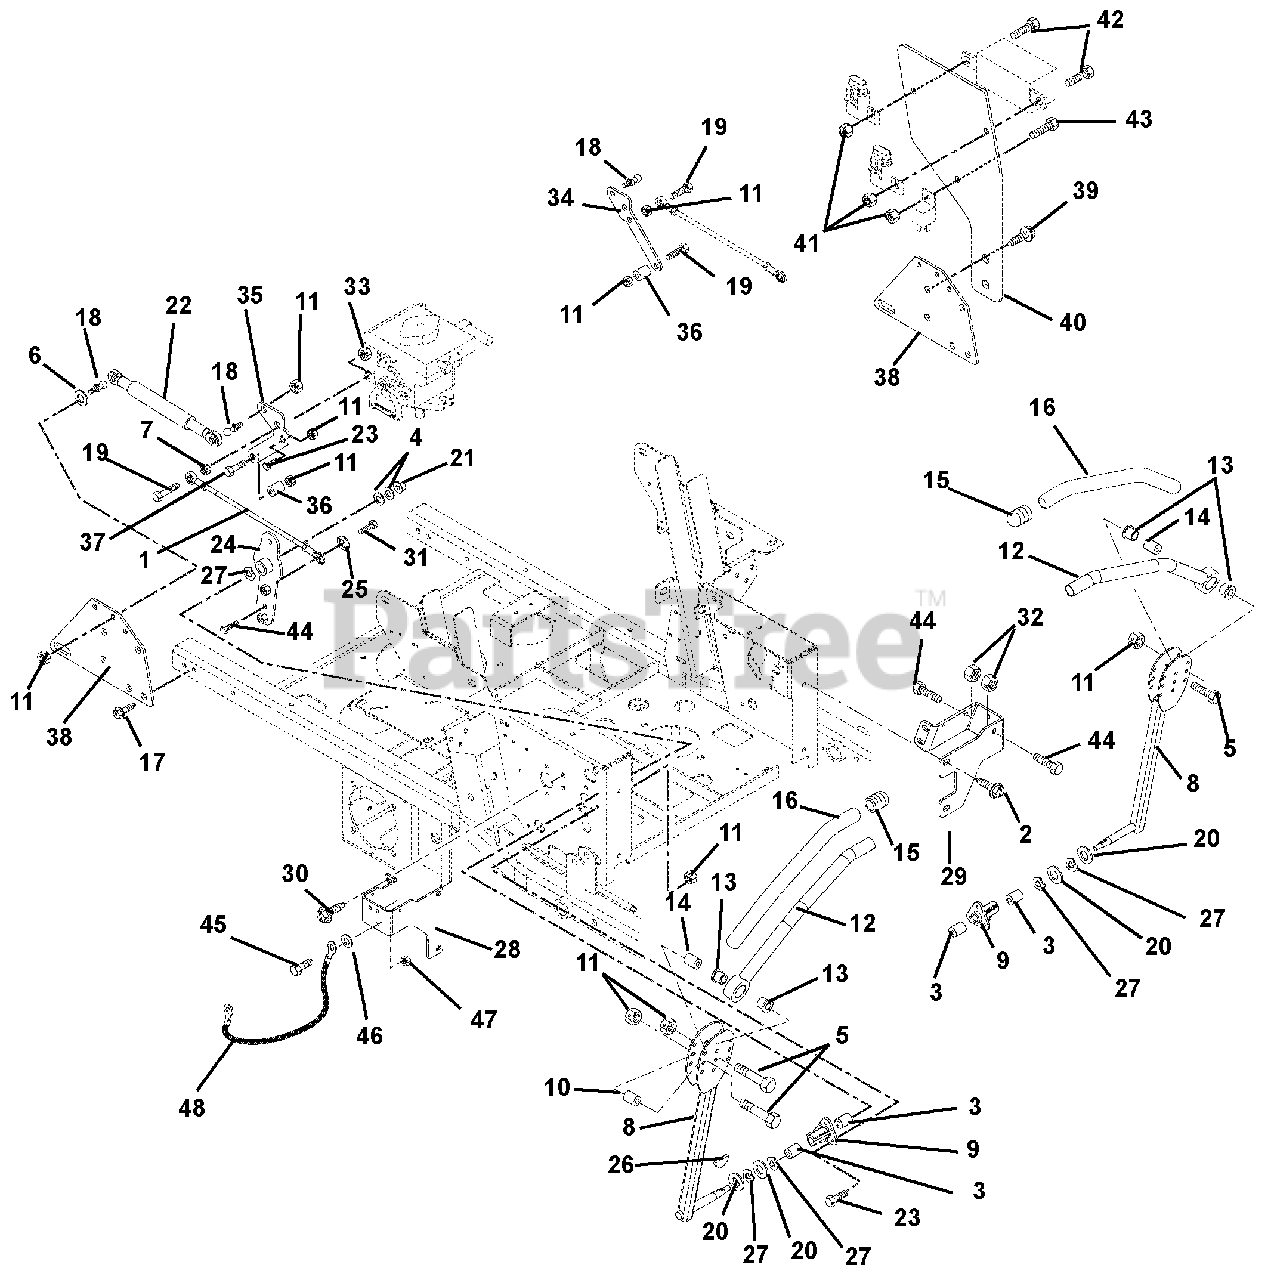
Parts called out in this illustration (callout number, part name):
1	Assembly, Steering Rod .38 Rod x 7.60
2	Screw, Tapping .38-16 x .75 Hex Washer Head
3	Bushing .625 x .75 x .50
4	Washer, Flat Steel .403 x .812 x .065
5	Bolt, Hex .31-18 x 1.75 Grade 5
6	Washer, Flat Steel .344 x .688 x .065
7	Nut, Hex .38-16
8	Control Arm
9	Bushing, Flange
10	Eccentric
11	Nut, Locking Top Flange .31-18
12	Handle Weldment Left-Hand
13	Bushing, Flange Nylon .762 x 1.48 x .44
15	Caplug, Handlebar
16	Grip, Handlebar
17	Screw, Tapping .31-18 x .50 Hex Washer Head
18	Stud, Ball
19	Bolt, Hex .38-16 x 1.50 Grade 5
20	Washer, Flat Steel .63 x 1.005 x .062
21	Nut, Locking Top Flange .38-16
22	Damper, Control
23	Bolt, Hex .31-18 x .75 Grade 5
24	Weldment, Pivot Arm
25	Washer, Locking .38 x .094 Regular
26	Key, Woodruff .13 x .63
27	Washer, Wave
28	Stop, Steering Right Hand
29	Stop, Steering Left Hand
30	Screw, Tapping .38-16 x .50 Hex Washer Head
31	Bolt, Hex .38-16 x 1.25 Grade 5
32	Nut, Hex Jam .375-16
33	Nut, Locking Center .38-16
34	Bracket, Left Hand
35	Bracket, Right Hand
36	Spacer .318 x .43 x .375
37	Bolt, Hex .31-18 x 1.25 Grade 5
38	Bracket, Damper
39	Screw, Tapping .38-16 x .50 Hex Washer Head (091, 107)
40	Bracket, EFI Box Mount (091, 107)
41	Nut, Locking Nylon 10-24 with Insert (091, 107)
42	Screw, Machine 10-24 x 2.00 Hex Washer Head (091, 107)
43	Screw, Machine 10-24 x .50 Hex Washer Head (091, 107)
44	Bolt-Hex .375-16 x 1.75 Full Thread
45	Bolt-Hex .25-20 x .75 Grade 5
46	Washer, Flat Steel .265 x .50 x .087
47	Nut, Locking Top Flange .25-20
48	Cable, Hood
